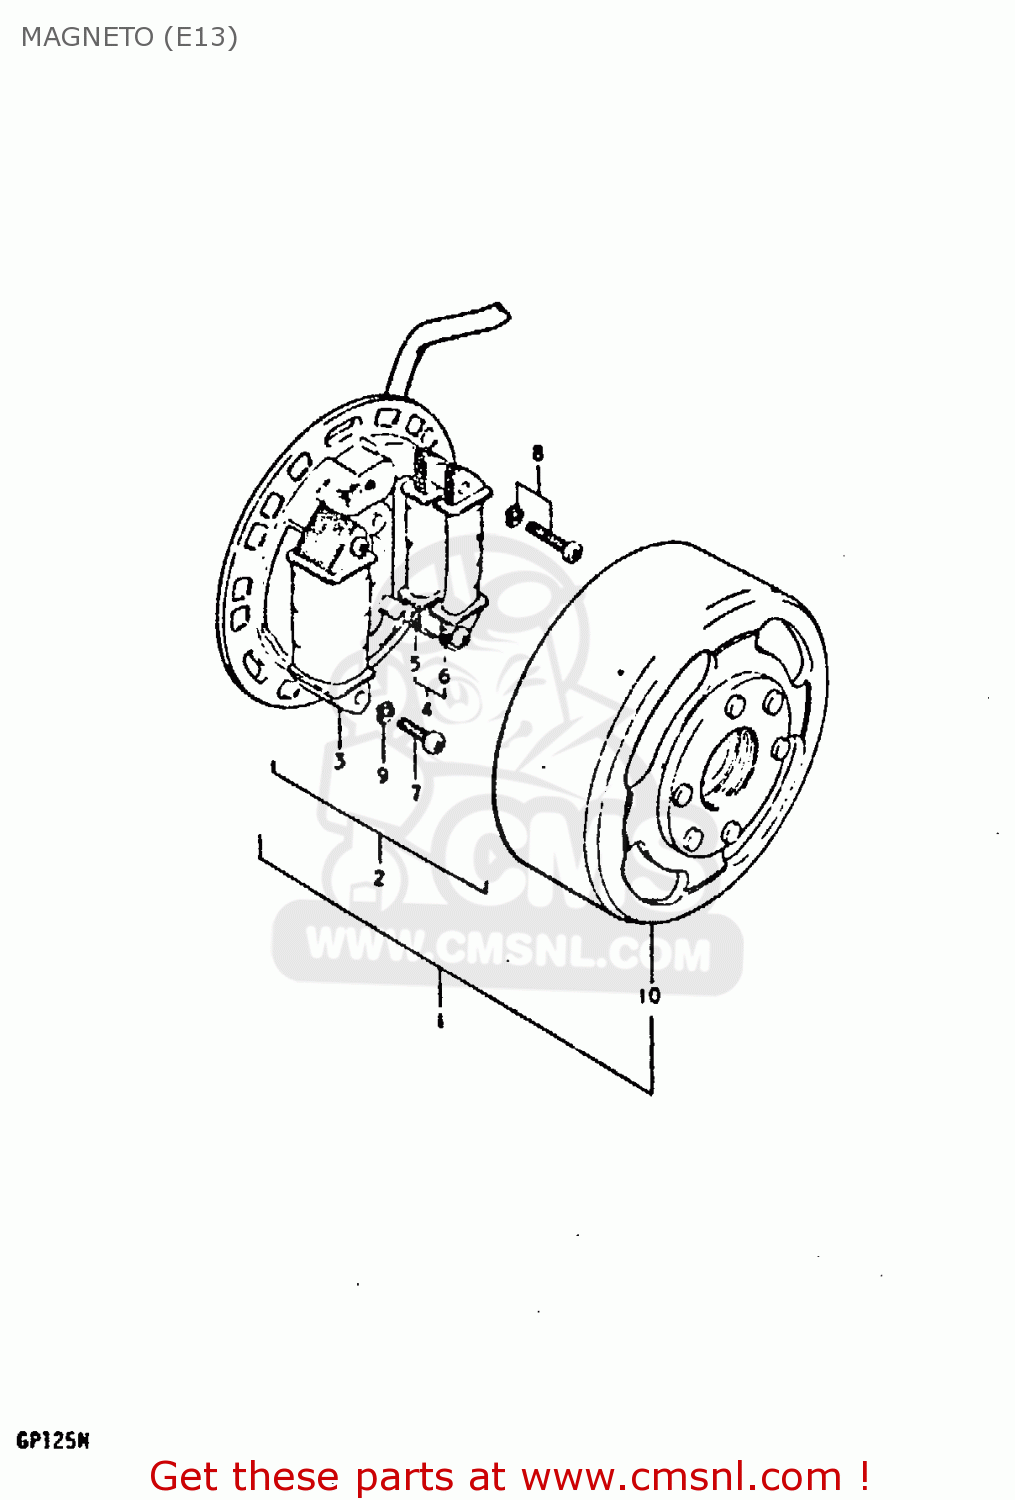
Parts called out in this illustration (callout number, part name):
1	MAGNETO ASSY
2	STATOR ASSY
3	COIL,LIGHTING
4	COIL, IGNITION
5	COIL, IGNITION (1)
6	COIL, IGNITION (2)
7	SCREW 4X25
8	SCREW
9	LOCK WASHER
10	ROTOR
